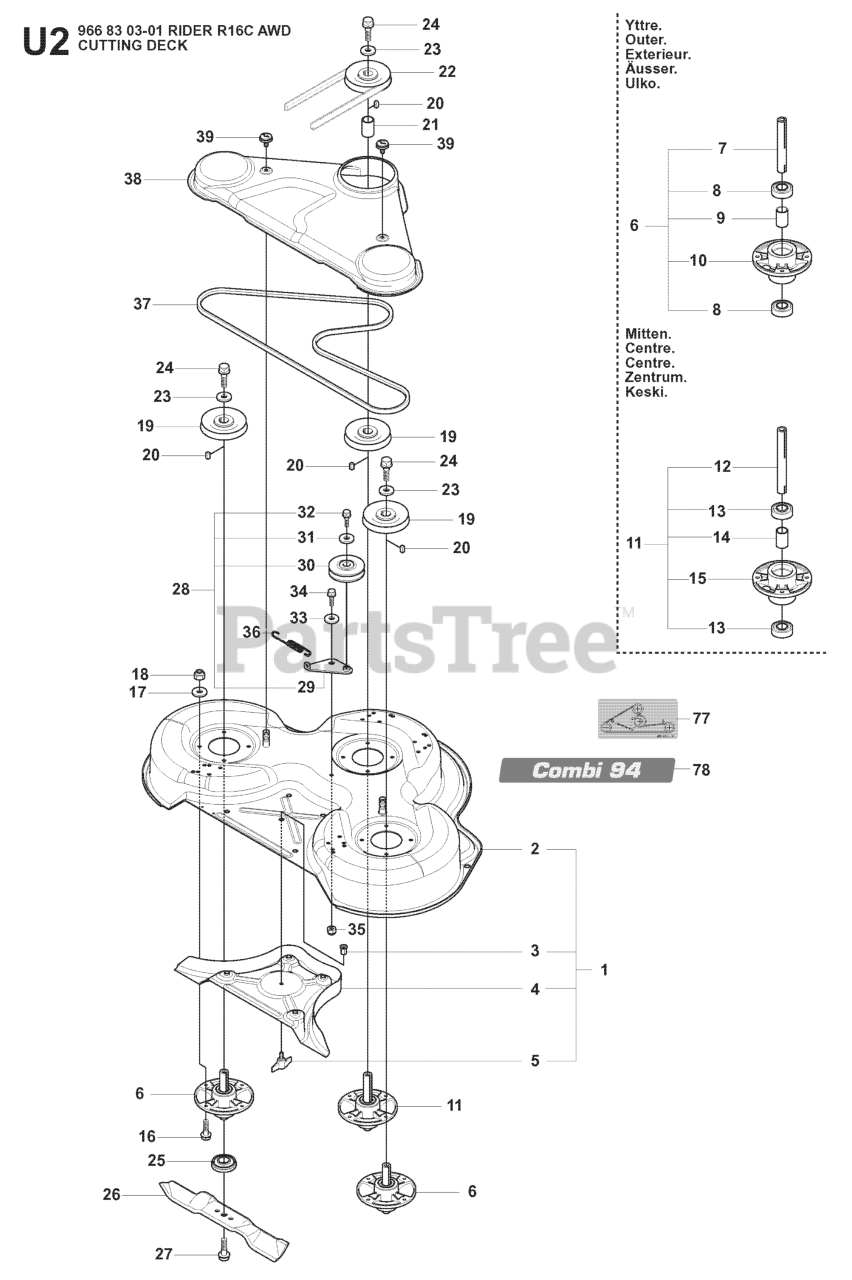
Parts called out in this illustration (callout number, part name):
4	PLUG C93 & C94
6	RP SPINDLE ASSY
10	BEARING HOUSING
15	BEARING HOUSING
17	WASHER BRB 8.4X17
18	LOCKNUT M8
21	SPACING SLEEVE
25	BLADE BRACKET
30	PULLEY
33	WASHER
35	LOCKNUT M8
38	BELT COVER C93 & C94 GREY
